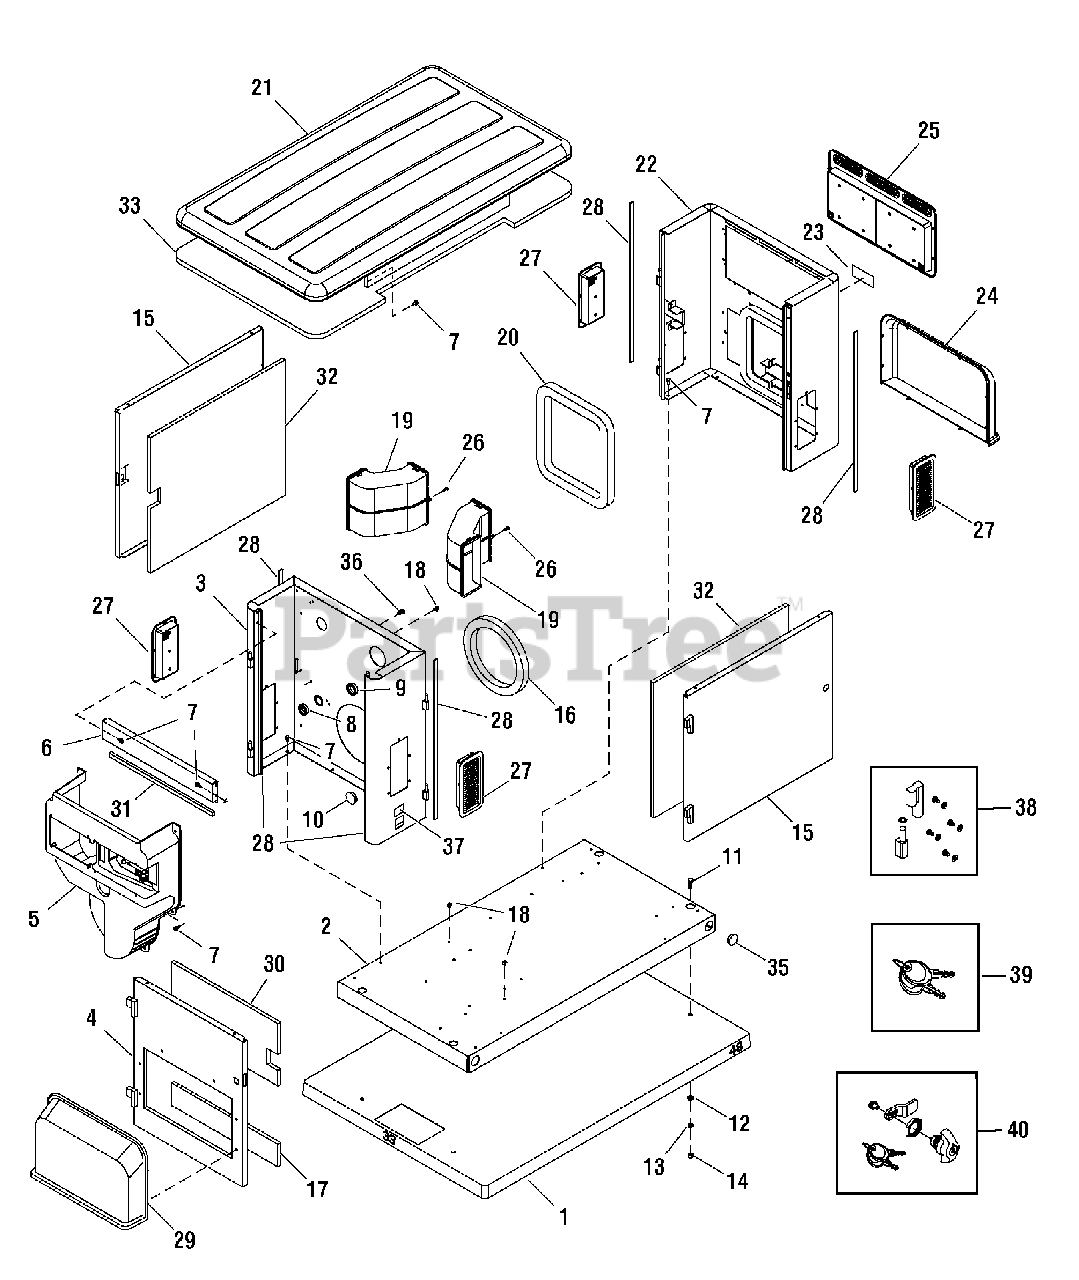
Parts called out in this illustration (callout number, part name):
3	BULKHEAD ASSEMBLY, Engine
6	SUPPORT RAIL ASSEMBLY
7	BOLT
11	* CAPSCREW, Hex, Head, 3/8-16 x 1
12	* WASHER, Flat, 3/8-M10
13	* WASHER, Lock, 3/8
14	* NUT, 3/8-16
16	SEAL, Foam
22	BULKHEAD ASSEMBLY, Alternator
24	COVER, Air Intake
29	COVER, Air Intake
37	DECAL, Fuel Inlet
